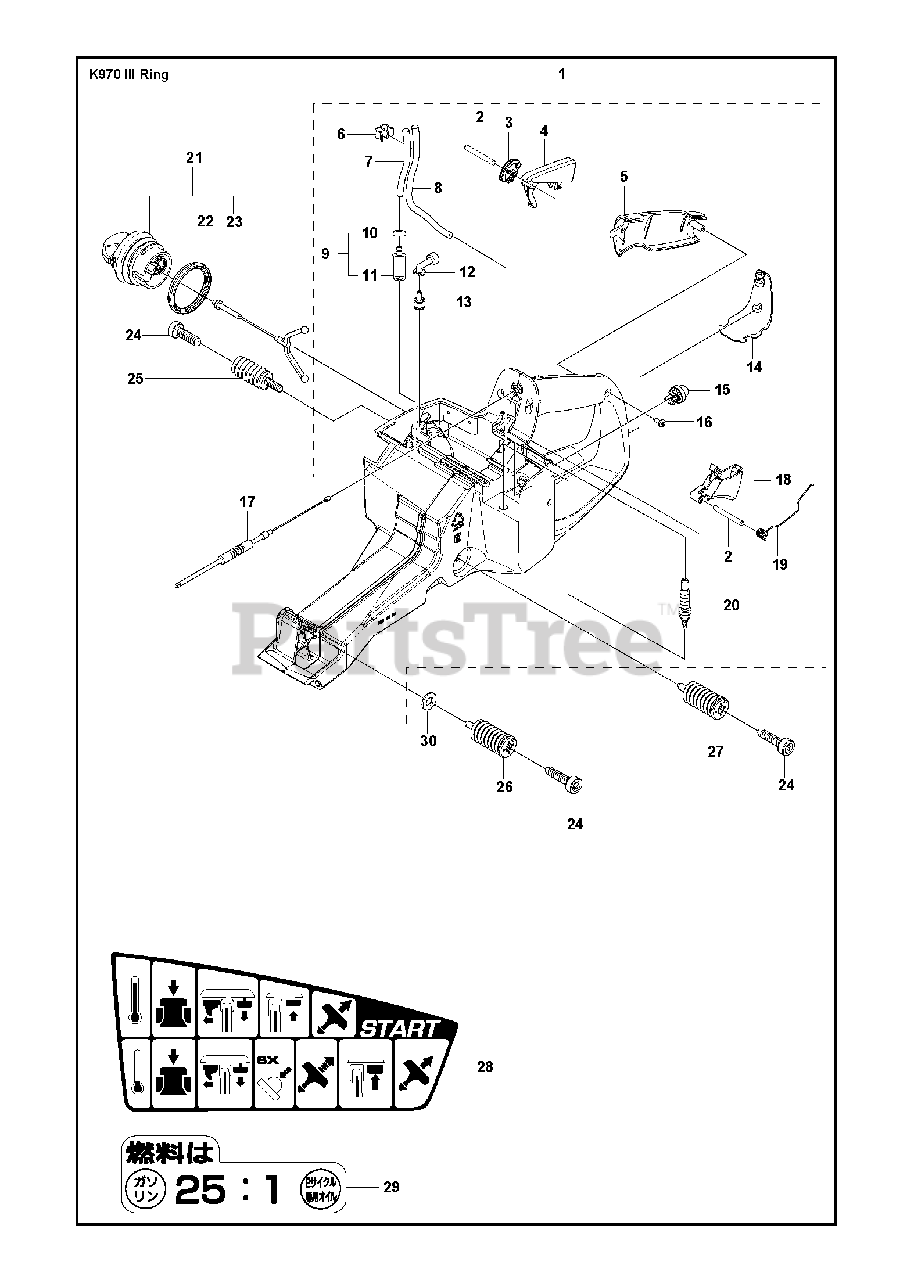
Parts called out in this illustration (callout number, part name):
2	PARALLEL PIN
4	THROTTLE LOCKOUT
7	FUEL HOSE
12	TANK VENT ASSY
13	TANK VENT ASSY
14	GROUND SUPPORT
16	SCREW CITXPANT
17	THROTTLE CABLE ASSY
18	THROTTLE CONTROL
21	TANK CAP ASSY
24	SCREW ITXSCM
25	ANTIVIBRATION ELEMENT
26	ANTIVIBRATION ELEMENT
27	ANTIVIBRATION ELEMENT
